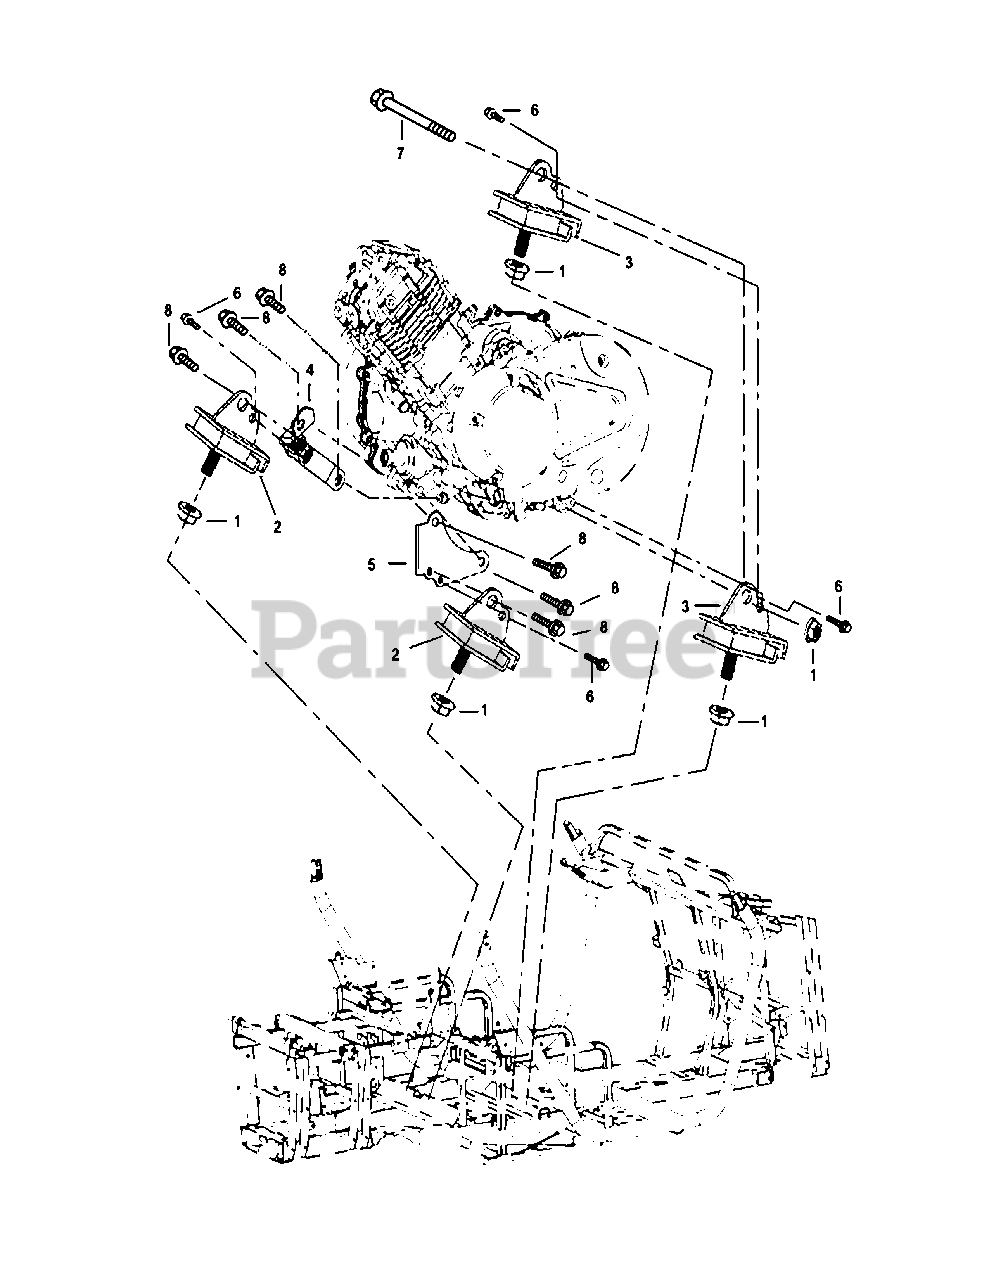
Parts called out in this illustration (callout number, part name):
1	Hexagon flange nut M10×1.25
2	Rear Suspension Support, Engine
3	Front Suspension Support, Engine
4	Right Lower Support ,Engine
5	Left Lower Support, Engine
6	Hexagon Flange Bolt M6×16
7	Hexagon Flange Bolt M10×1.25×170
8	Hexagon Flange Bolt M8×16
